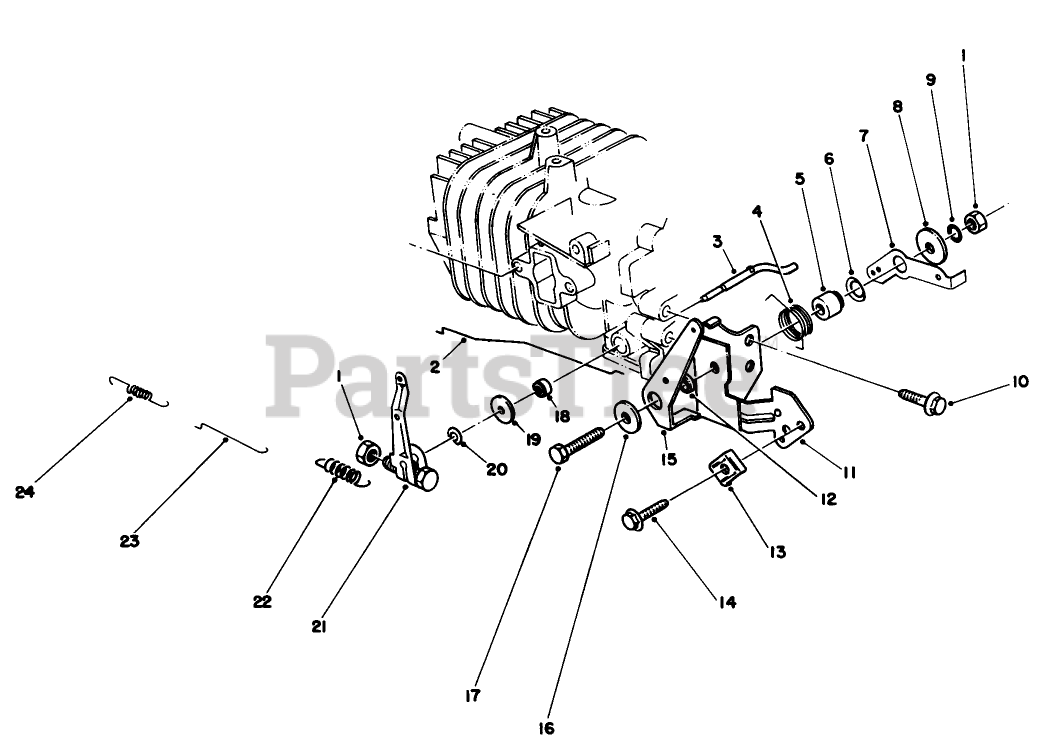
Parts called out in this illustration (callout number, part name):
4	SPRING-CHOKE LEVER
7	LEVER-SPRING, GOVERNOR
8	WASHER
9	LOCKWASHER
11	BRACKET-THROTTLE, CONTROL
12	SPACER-CHOKE LEVER
13	CLAMP
18	SEAL-OIL
19	WASHER
22	SPRING-GOVERNOR
23	ROD-CARBURETOR
24	SPRING
